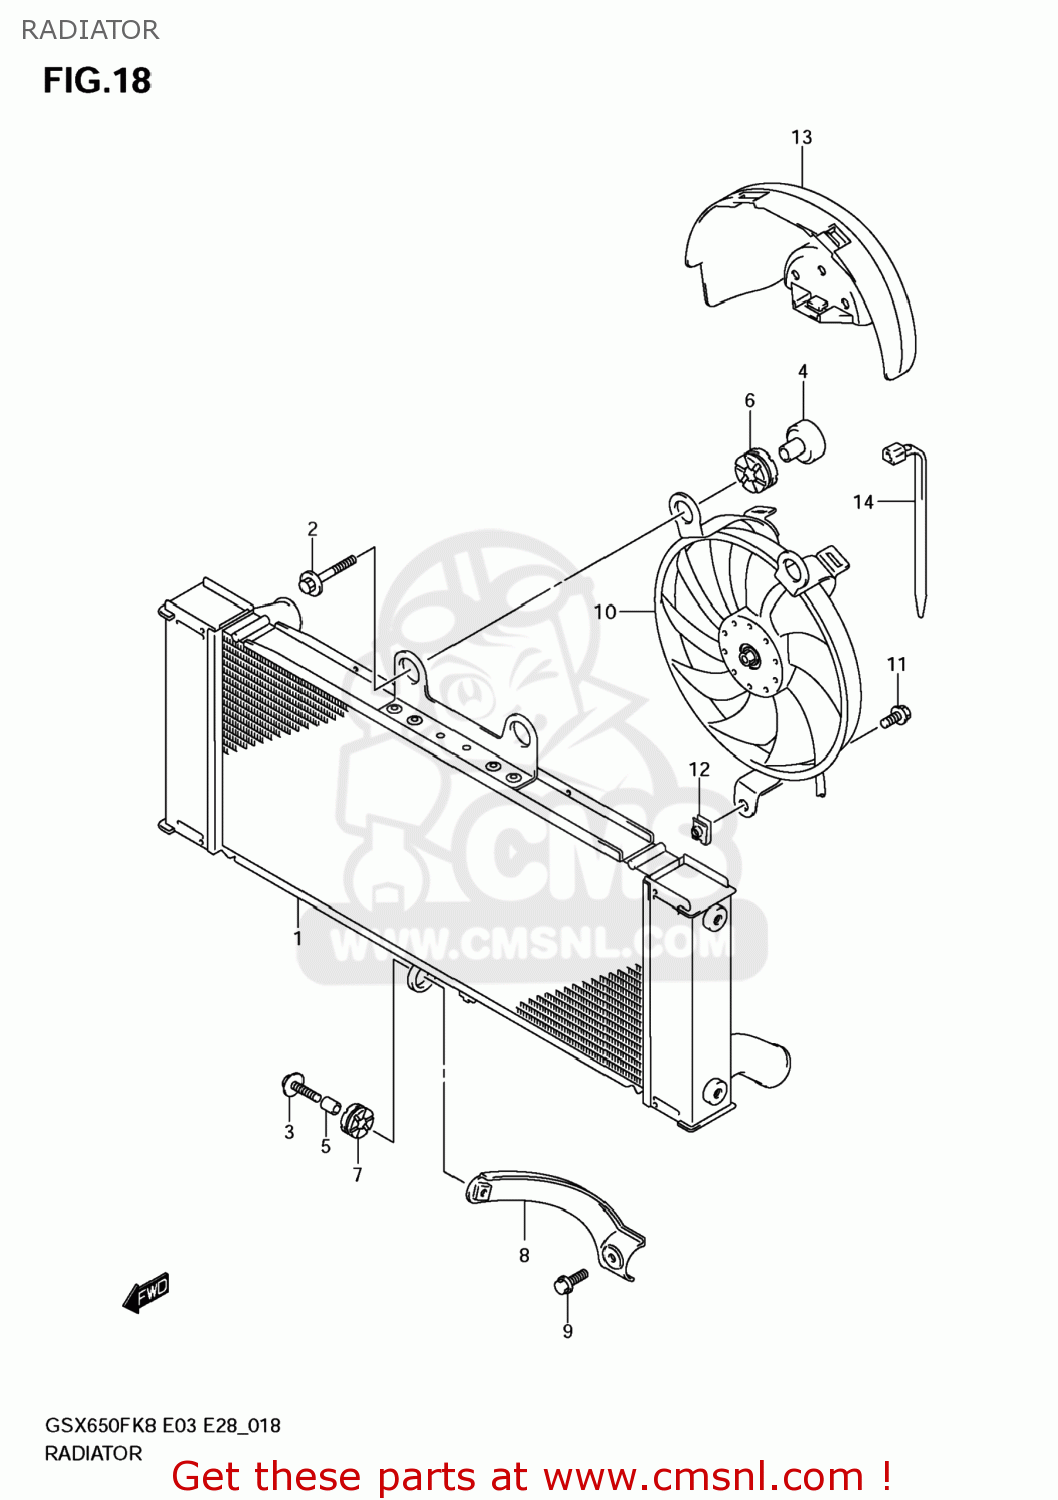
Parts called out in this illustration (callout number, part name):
1	RADIATOR ASSY,WATER
2	BOLT(6X37)
3	BOLT(6X25)
4	SPACER,RADIATOR UPR
5	SPACER(6.5X10X12)
6	CUSHION
7	CUSHION
8	BRACKET COMP,R
9	BOLT
10	FAN ASSY,RADIATOR
11	BOLT
12	NUT,RADIATOR FAN
13	SHIELD,RADIATOR HEAT
14	CLAMP(L:125)
